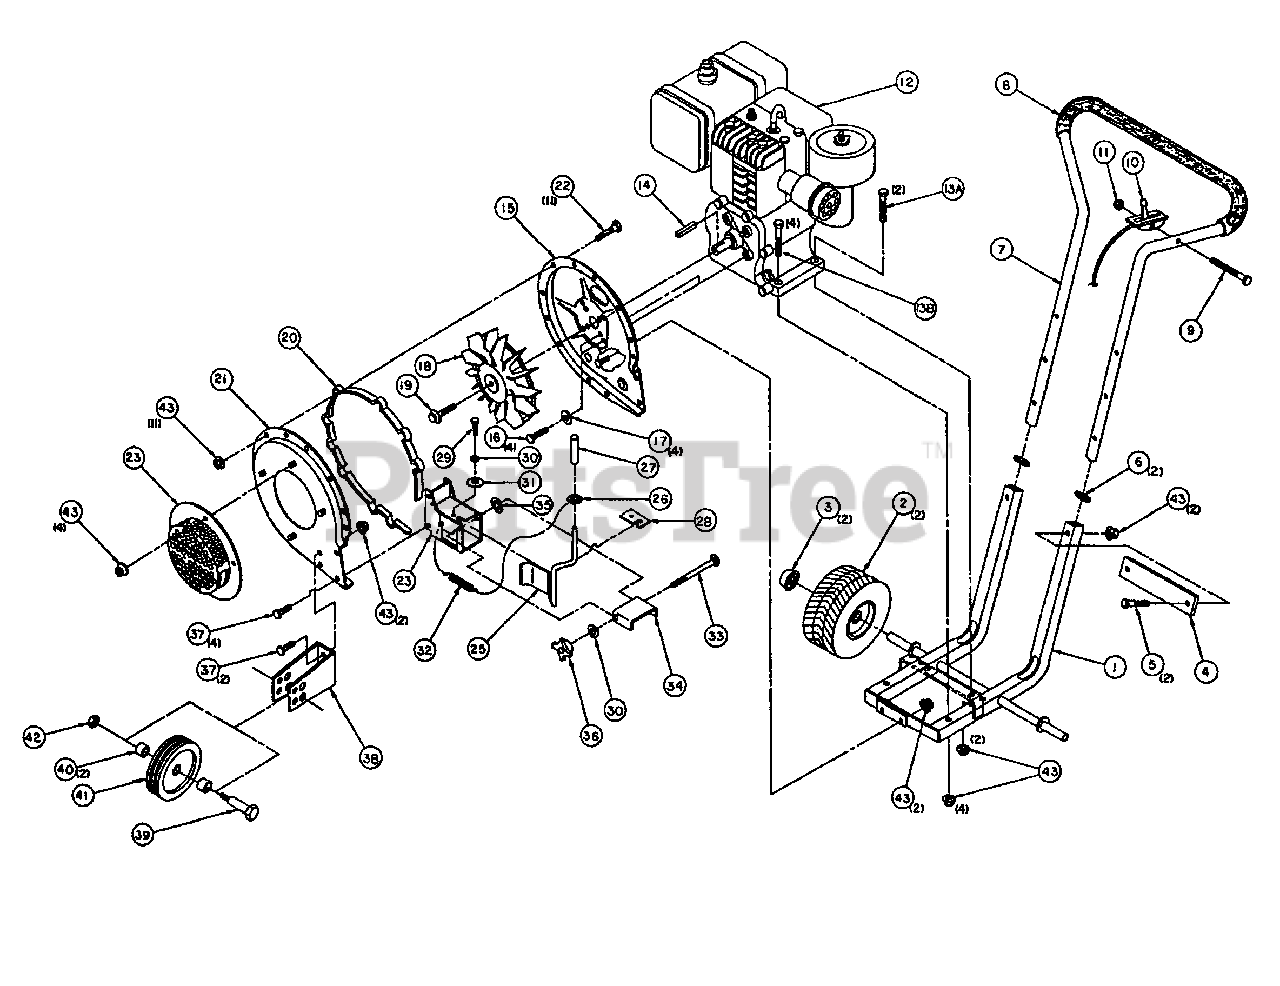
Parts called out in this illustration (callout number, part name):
1	Lower Handle Bar Assembly
2	Wheel 4.10 x 3.50 x 4
3	Push Nut Cap
4	Upper Lifting Handle
5	5/16-18 x 1-3/4" HHCS Pltd
6	Washer Handle Bar
7	Upper Handlebar Assembly
8	Grip, Handlebar
9	1/4-20 x 1-1/2" HHCS Pltd
10	Throttle Control
11	1/4-20 Flex Locknut Pltd
13A	5/16-18 x 1-1/2" HHCS Pltd
13B	5/16-18 x 2-3/4" HHCS Pltd
14	1/4" x 1/4" x 2" Lg. Shaft Key
15	Engine Housing
16	5/16-24 x 3/4" HHCS
17	5/16" Split Lockwasher Pltd
18	Impeller
19	3/8-24 x 1-1/4" HHCS Pltd
20	Housing Spacer
21	Front Housing
22	5/16-18 x 1-1/2" HHCS
23	Impeller Cover
25	Diverter Weld Assembly
26	3/8" Internal Lockwasher Pltd.
27	Vinyl Grip, Diverter Handle
28	Diverter Clip
29	1/4-20 x 1/2" HHCS Pltd
30	1/4" Split Lockwasher Pltd
31	1/4" Flat Washer Pltd
32	Spring, Diverter
33	1/4-20 x 6" Lg. Carriage Bolt
34	Deflector
35	1/4" Internal Lockwasher Pltd
36	Adjustment Knob
37	5/16-18 x 5/8" HHCS, GR5
38	Front Wheel Bracket
39	Hex Head Shoulder Bolt
40	Spacer, Wheel
41	Front Wheel
42	3/8-16 Gripco Locknut
43	5/16-18 Whiz Locknut Pltd
